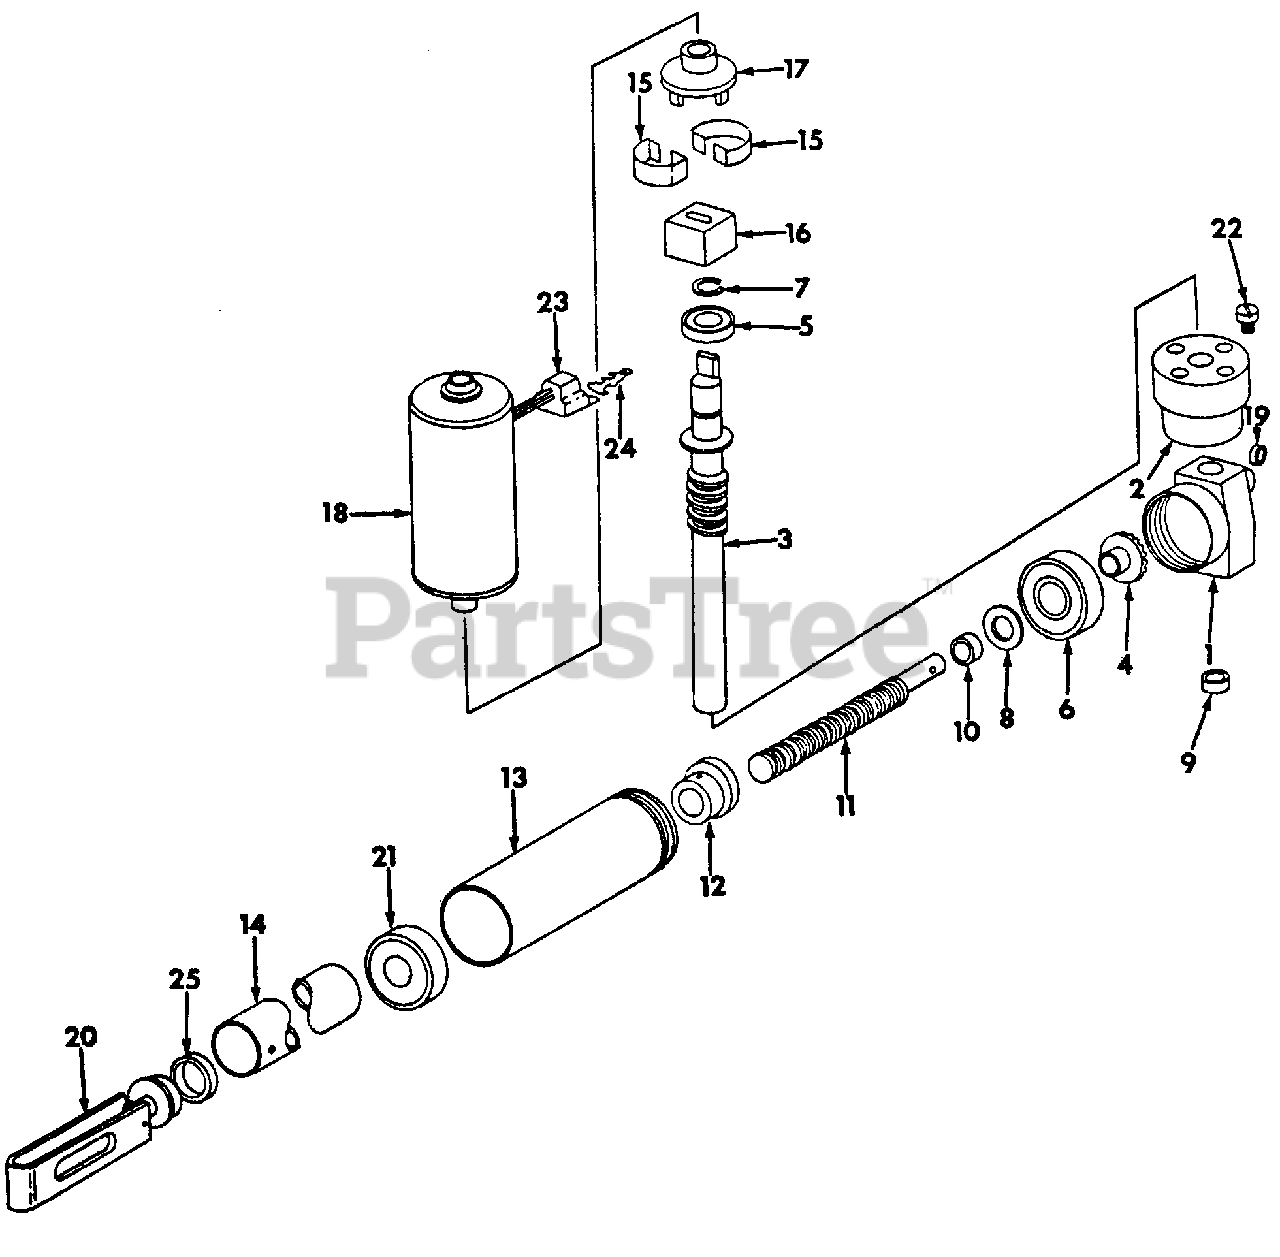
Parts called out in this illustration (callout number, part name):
2	Adapter, Motor
3	Pinion, Spiroid
4	Gear, Spiroid
5	Bearing, Pinion
6	Bearing, Load
7	Ring, Retaining
9	Bushing, Pinion
10	Bushing, Screw
12	Nut, Lifting
13	Tube, Outer
14	Tube, Translating
15	Spring, Brake
17	Coupling, Drive
18	Motor, Permanent Magnet
19	Bushing, Housing Clevis
20	Clevis Assy
22	Screw, Tap Tite
23	Connector, Multiple
25	Bushing, Guide
